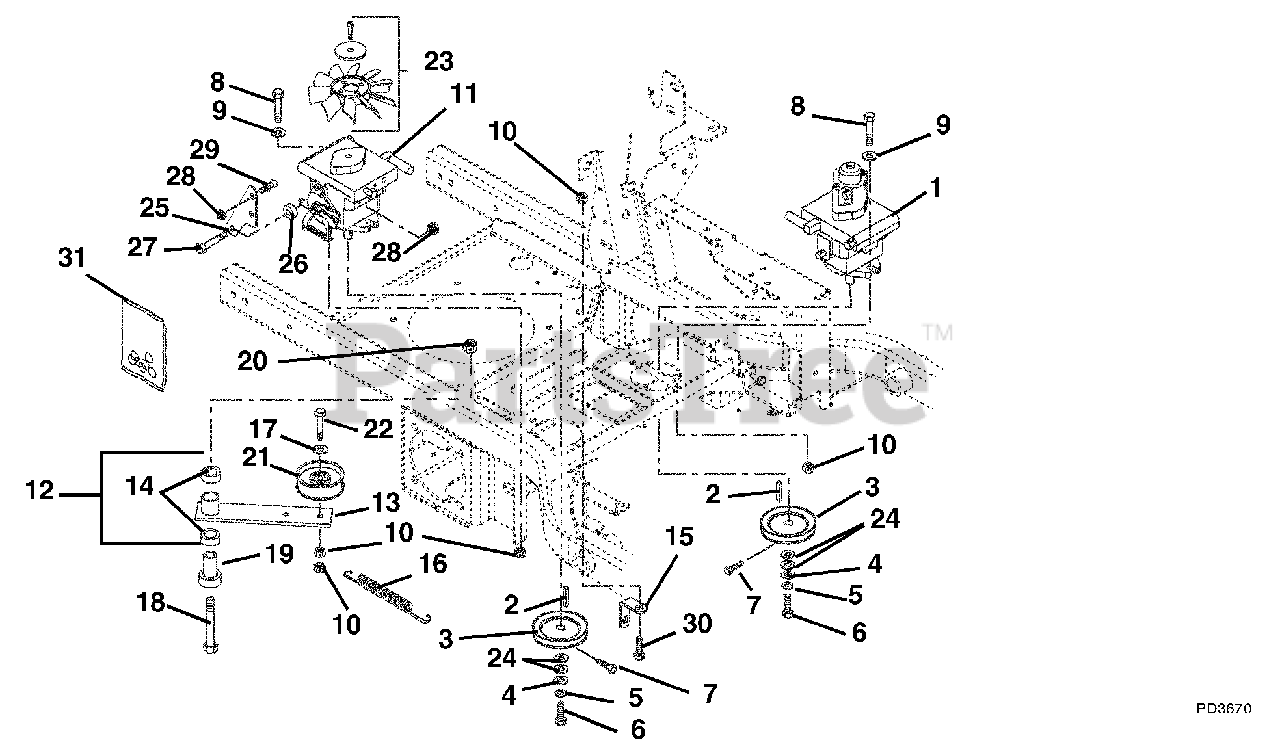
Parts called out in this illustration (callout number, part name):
1	Hydrostat BDP with Auxiliary
2	Key-Straight 5mm x 25mm x 5mm
3	Sheave 4.0 x .199
4	Washer-Flat-Steel .281 x 1.00 x .063
5	Washer-Locking .25 x .062
6	Bolt-Hex M6 x 1.0 x 12
7	Bolt-Hex .25-20 x .50 Grade 5
8	Bolt-Hex .38-16 x 1.25 Grade 5
9	Washer-Flat-Steel .39 x .75 x .125
10	Nut-Locking-Top-Flange .38-16
12	Assembly,Idler Arm Guard Drive
13	Weldment, Idler Arm Ground Drive
14	Bearing, 1.00 x 1.12 x .75
15	Anchor-Spring-Idler
16	Spring-Tension .120 x .845 x 6.500
17	Washer-Flat-Steel .39 x.75 x.125
18	Bolt-Hex .50-13 x 3.50 Grade 5
19	Bearing, Pedestal Powdered Metal
20	Nut-Locking-Top-Flange .50-13
21	Idler, Flat 4.00 x 1.06
22	Bolt-Hex .38-16 x 2.25 Grade 5
23	Fan, Cooling
24	Washer-Flat-Steel .656 x 1.31 x .095
25	Bracket, Return to Neutral/Damper
26	Spacer .344 x 1.00 x .375
27	Bolt-Hex .31-18 x 1.25 Grade 5
28	Nut-Locking-Top-Flange .31-18
29	Stud- Ball
30	Bolt-Hex .38-16 x .75 Grade 5
31	Kit, Pump Seal (BDP-10A)
